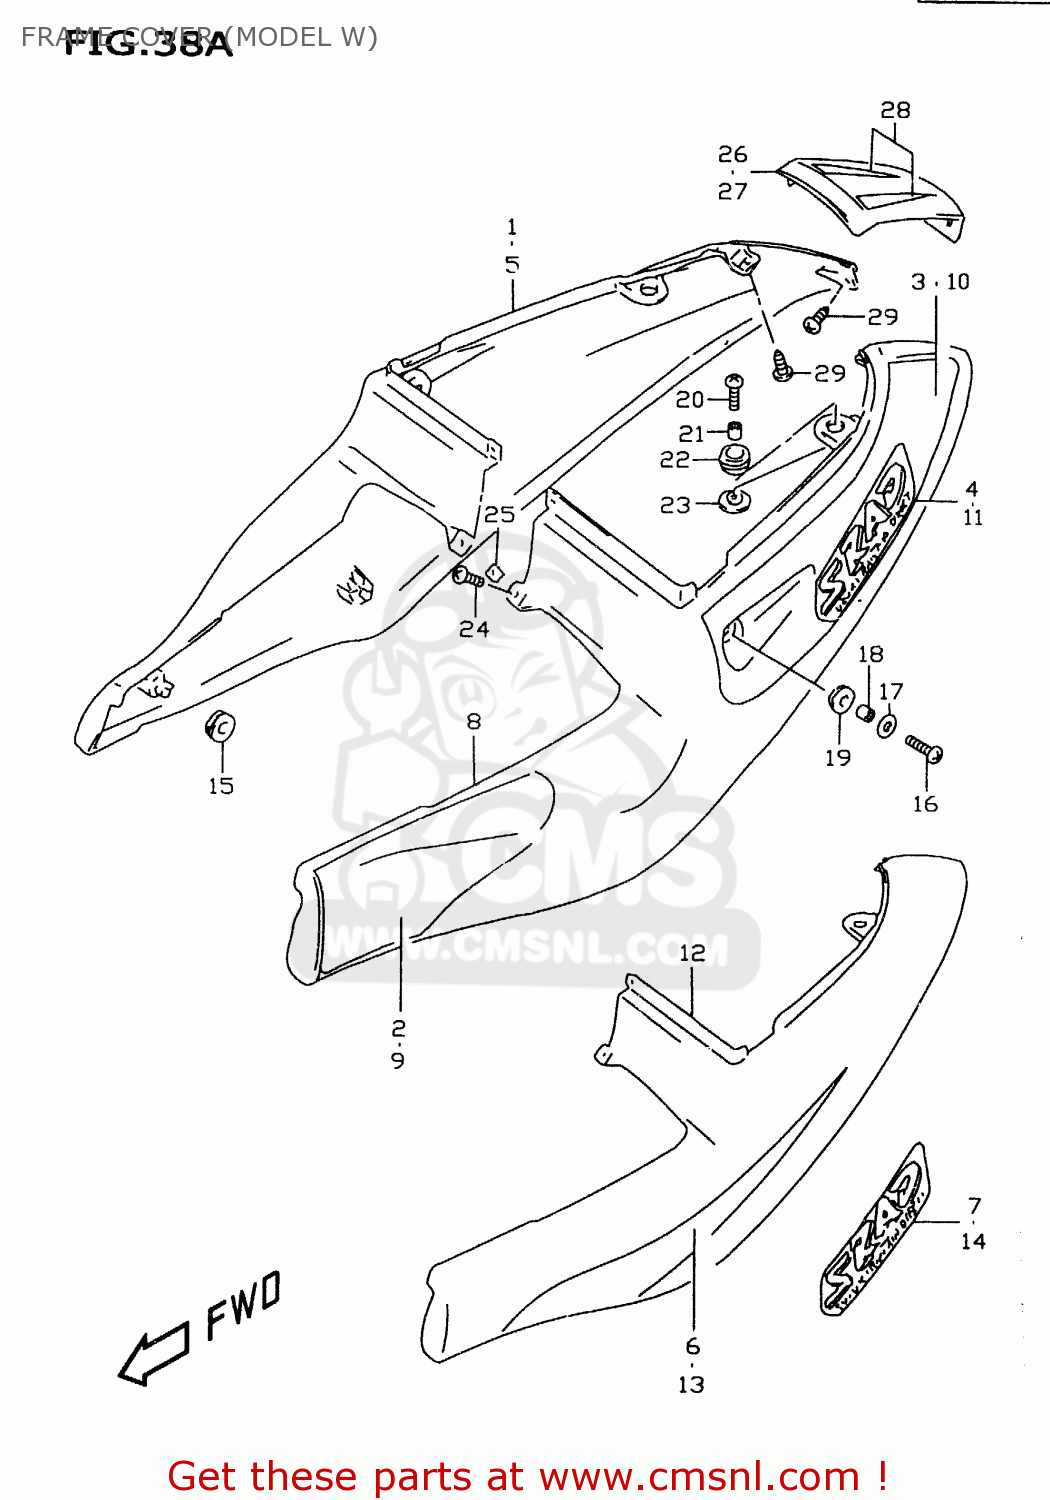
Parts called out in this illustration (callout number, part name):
1	COVER,FRAME,R(BLACK)
2	TAPE,FRAME COVER,RIGHT NO
3	TAPE,FRAME COVER,R
4	EMBLEM,FRAME COVER
5	COVER,FRAME,R(WHITE)
6	TAPE,FRAME COVER,RIGHT
7	EMBLEM,FRAME COVER
8	COVER,FRAME,L(BLACK)
9	TAPE,FRAME COVER NO.1,L
10	TAPE,FRAME COVER,L
11	EMBLEM,FRAME COVER
12	COVER,FRAME,L(WHITE)
13	TAPE,FRAME COVER,LEFT
14	EMBLEM,FRAME COVER
15	CUSHION
16	SCREW(6X20)
17	WASHER(6.5X22X1.6)
18	SCREW(6X25)
19	CUSHION
20	CUSHION,TAIL COVER UPR
21	CUSHION,FRAME COVER LWR
22	SCREW
23	NUT
24	COVER,FRAME CTR
25	COVER,FRAME CTR
26	TAPE SET,FRAME COVER CTR
27	SCREW
